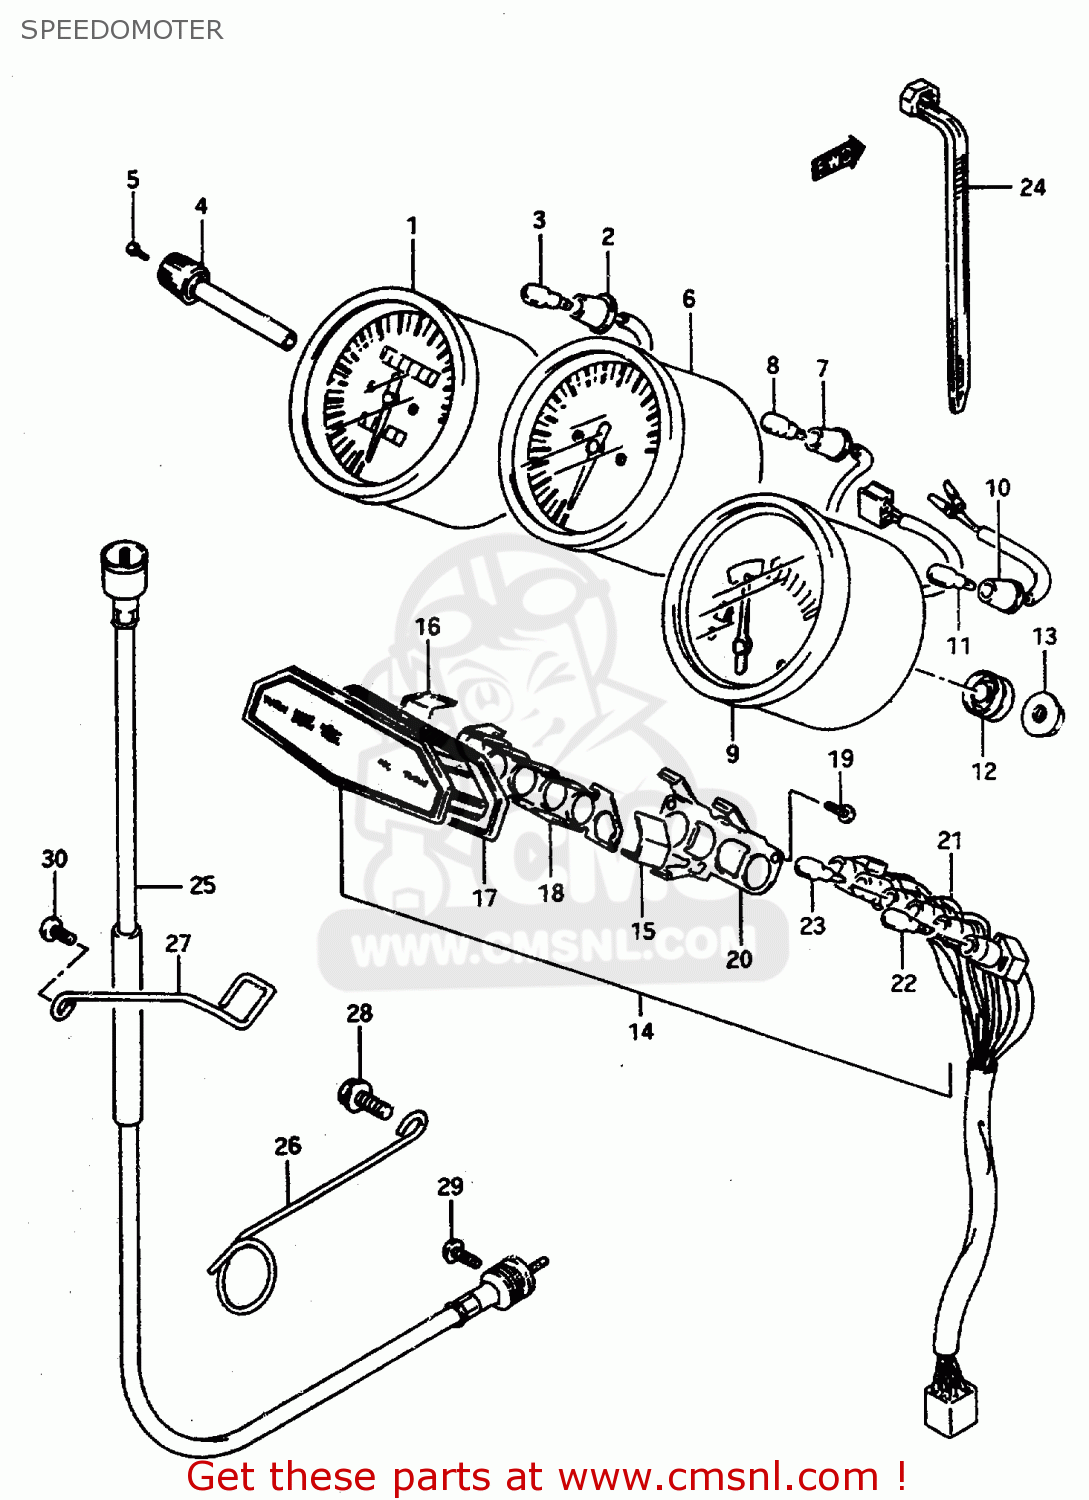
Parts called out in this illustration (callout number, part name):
1	SPEEDOMETER ASSY
2	SOCKET
3	BULB(12V3W,WB371,T7)
4	KNOB,TRIP
5	SCREW,TRIP KNOB
6	TACHOMETER ASSY
7	SOCKET
8	BULB(12V3W,WB371,T7)
9	FUEL,METER ASSY
10	SOCKET
11	BULB(12V3W,WB371,T7)
12	CUSHION
13	NUT
14	BOX ASSY
15	PLATE,TURN,R
16	PLATE,TURN,L
17	CUSHION
18	PLATE,PILOT LAMP
19	SCREW
20	LOCK PLATE
21	SOCKET
22	BULB(12V1.7W,WB372,T7)
23	BULB(12V3W,WB371,T7)
24	CLAMP(L:125)
25	CABLE ASSY,SPEEDOMETER
26	CLAMP,SPEEDOMETER CABLE
27	CLAMP,SPEEDOMETER CABLE
28	BOLT
29	SCREW
30	SCREW 5X12
